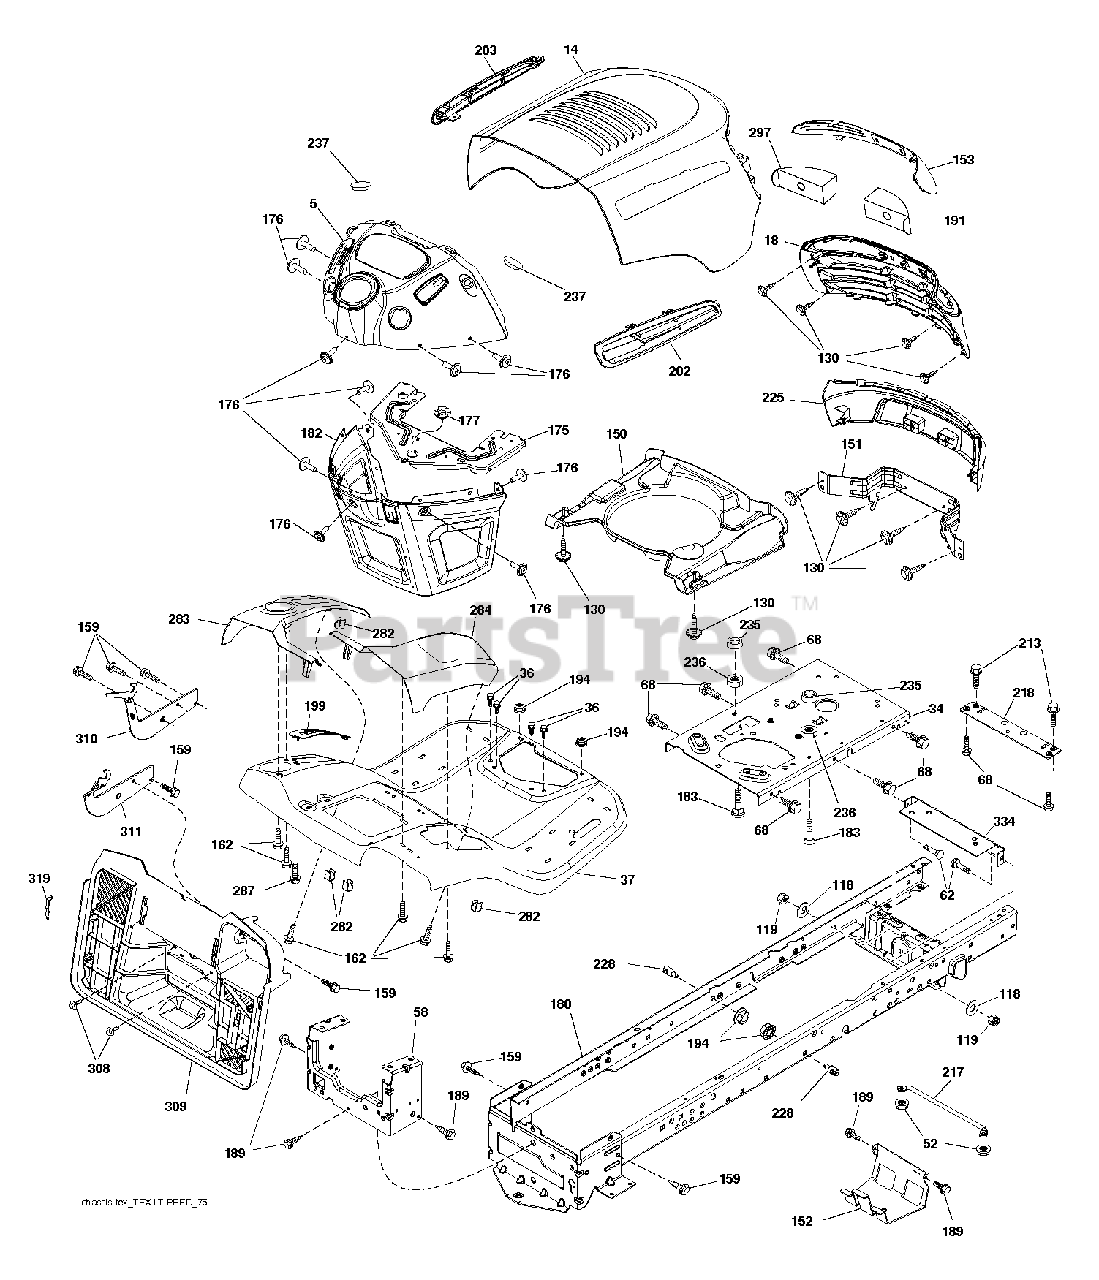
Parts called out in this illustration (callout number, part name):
5	DASH.LT.PRED.E.SRV.CKMTC.BLK
14	HOOD.PNT.PREDATOR.LT.TX.667
18	GRILLE.SVC.BASE.PREDATOR.LT428
34	PLATE .ENGINE.127".10GA.
36	SCREW 5/16"
37	FENDER.TEX.SRD.CRD.BASE
52	LOCKNUT
58	DRAWBAR UPPER 2PC SMALL FENDER
119	LOCKNUT
130	SCREW.#10 X 0.750.BOS THREAD
150	DUCT.AIR.PREDATOR.LT.2.36"
151	BRACKET.PIVOT.ALPHA.LT
152	SHIELD BROWNING
153	LENS.PREDATOR.LT
159	SCREW, 3/8-16X3/4
162	SCREW.HI-LO.CONSOLE
176	SCREW.#10-24X5/8.RN.QU
177	BUSHING STEERING
180	CHASSIS.WLDMNT.14GA.2PC.18".TI
182	DASH.LWER.PREDATOR/HUSQ.LT
183	BOLT.5/16-18X1-1/4 FULL THD
189	SCREW
191	INSERT.REFLECT.PREDATOR.LT.RH
194	NUT LOCK HEX FLANGE 5/16-18
203	VENT.SIDE.PRED.LT.LH.JONSERED
213	BOLT
217	ROD.PIVOT.HOOD
218	X-PIECE.HOOD.STOP.NON/
225	BUMPER.GRILLE.PRED.LT.JONS.505
228	STUD.FASTNER.W/ANTI-ROTATE
235	SPACER FENDER
236	NUT.CENTERLOCK.5/16-
237	PLUG.MOUNT.CARGO.BLK
282	CLIP.RETAINER.CONSOLE.LT.HUSQ
283	CONSOLE.DECKLIFT.LH.SRD.TEXCRD
284	CONSL.SHFT.PEDAL.RH.SRD.TEXCRD
297	REFLECTOR.INSERT.PRED.LH.LT
308	BOLT, 5/16-18 X 1 3/4
309	BACKPLATE.BAGGER.V2.SRD
310	LH.ADJUST.HANGER.BRACKET.ASM
311	RH.ADJUST.HANGER.BRACKET.ASM
319	BRACKET.ACTUATOR.BAGGER.SRD
334	Engine Bracket
